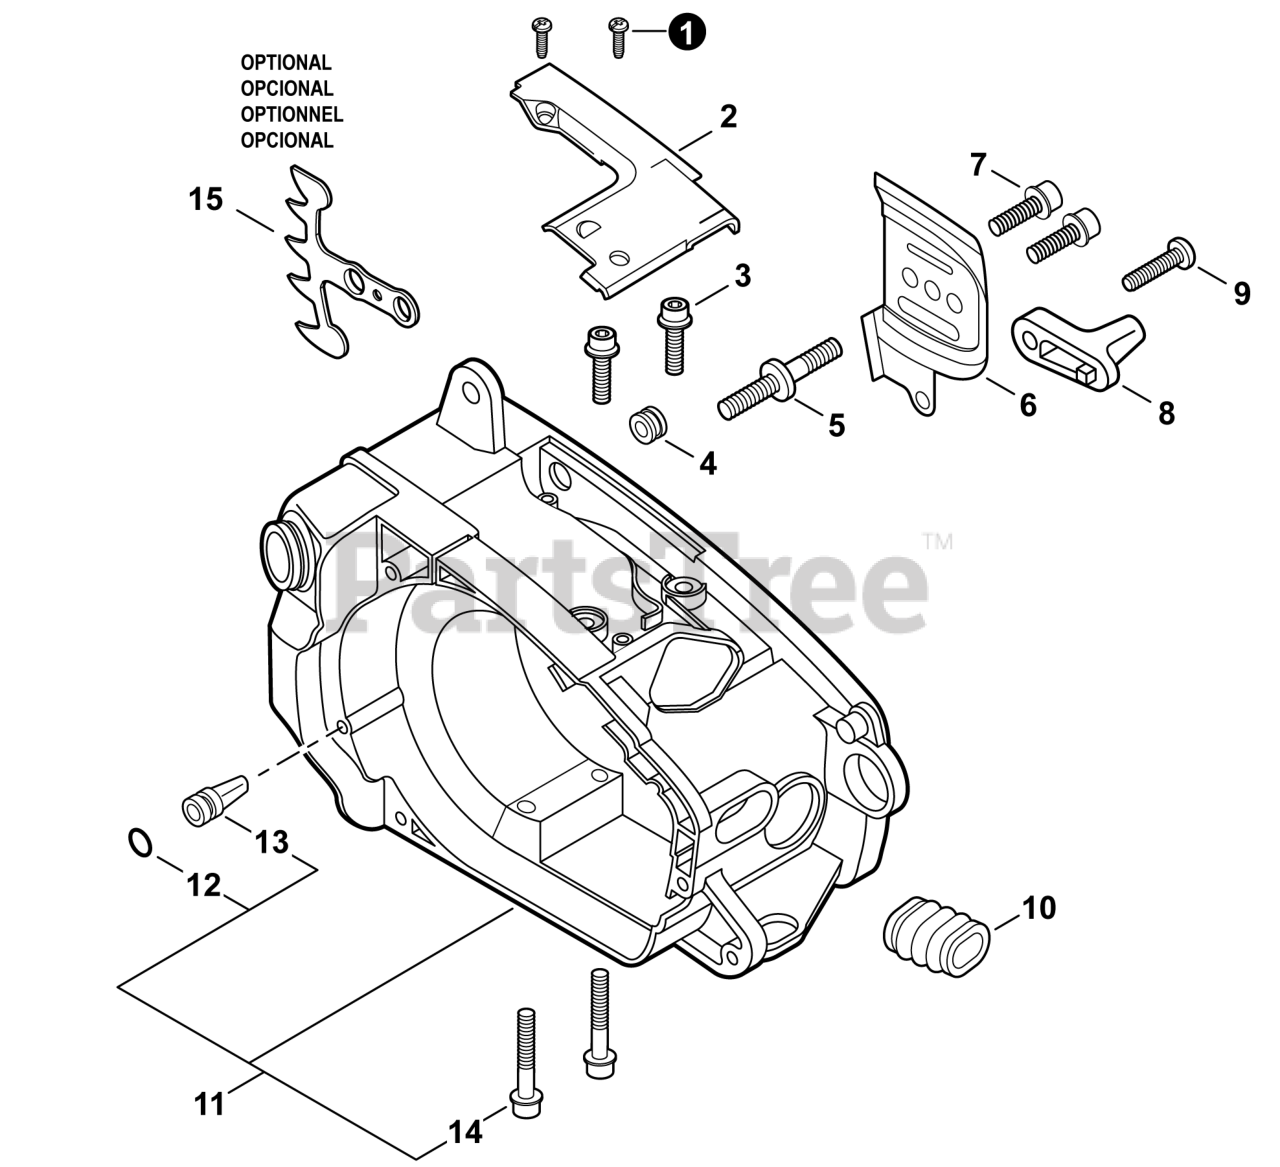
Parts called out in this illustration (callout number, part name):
1	SCREW 4×12
2	COVER, DUST
3	BOLT 5×18
5	BOLT, STUD 8
6	PLATE, GUIDE - INNER
7	BOLT 4×12
8	CHAIN CATCHER
9	SCREW, TAPPING 5×20
10	BELLOWS, INTAKE
11	COVER, ENGINE
13	CHECK VALVE
14	BOLT, FLANGE 5X25
15	SPIKE, BUMPER
